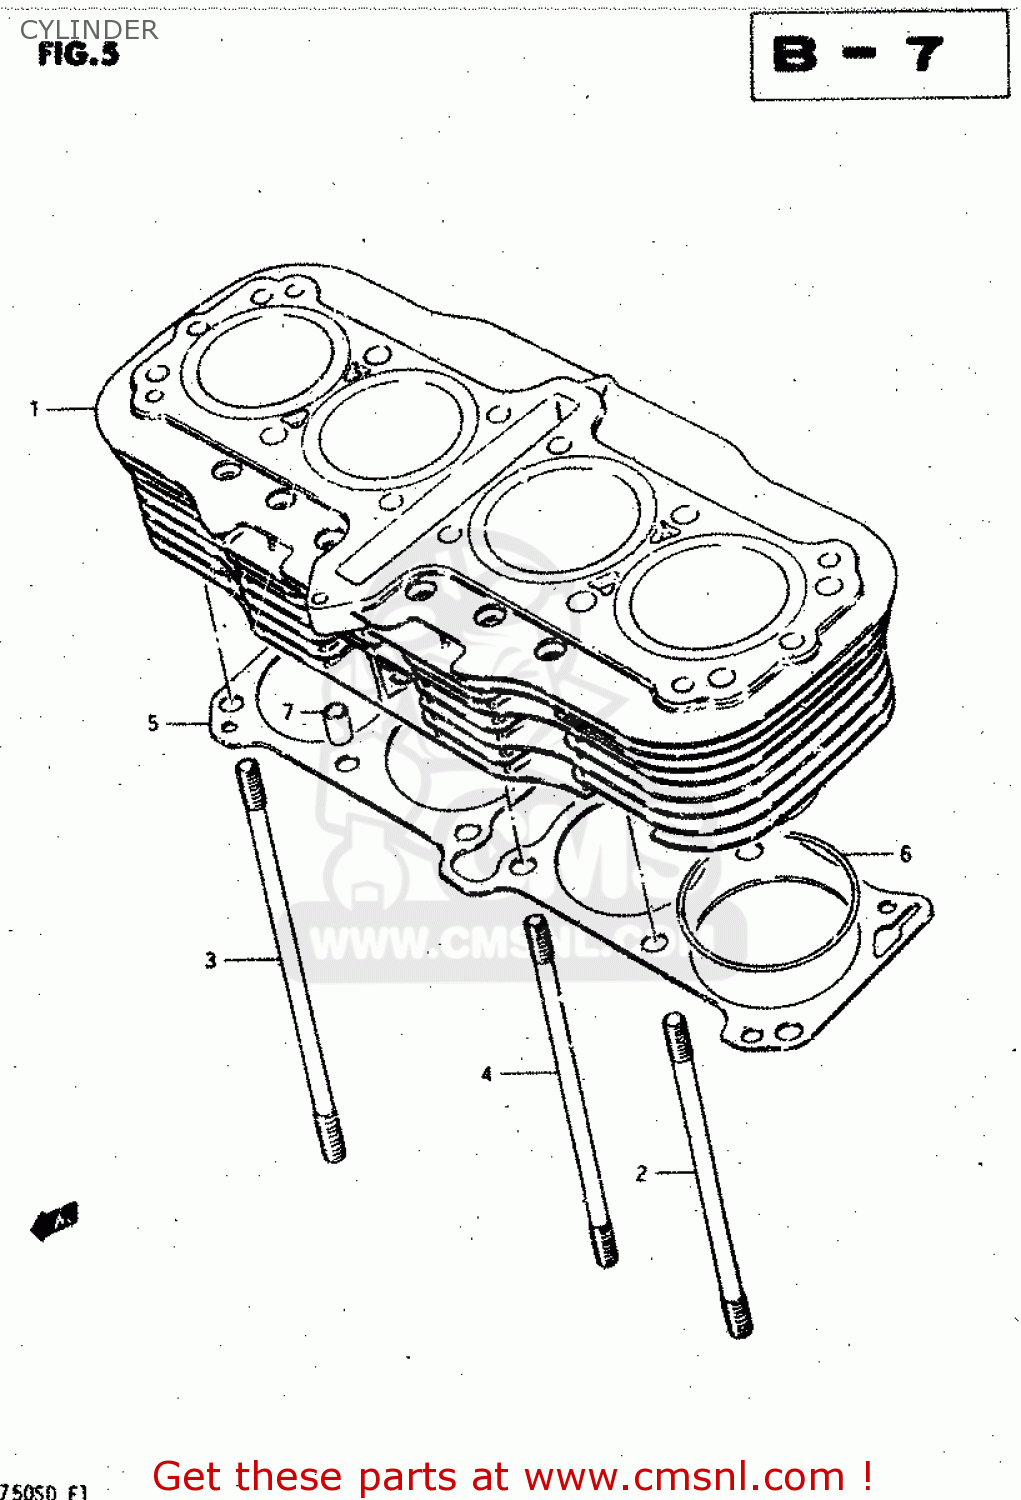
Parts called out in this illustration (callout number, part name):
1	CYLINDER
2	STUD
3	STUD
4	STUD
5	GASKET,CYLINDER (MCA)
6	O RING(D:2,ID:70)
7	PIN
